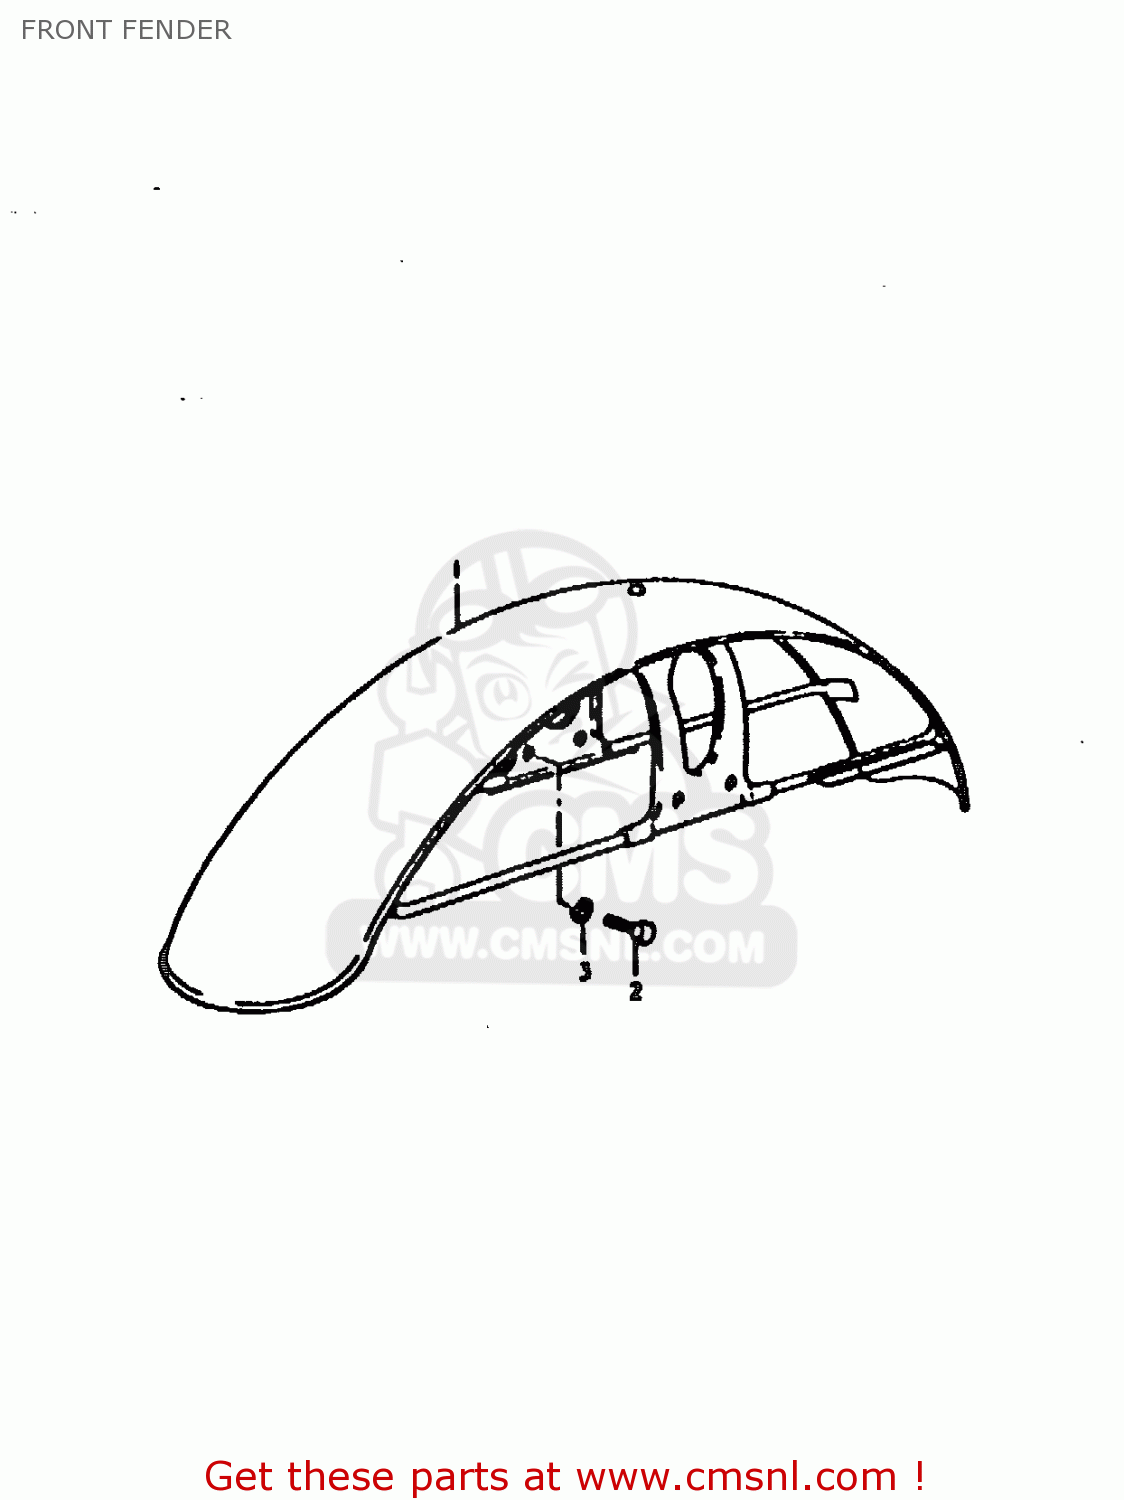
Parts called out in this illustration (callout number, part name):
1	FENDER, FRONT
2	BOLT
3	LOCK WASHER
